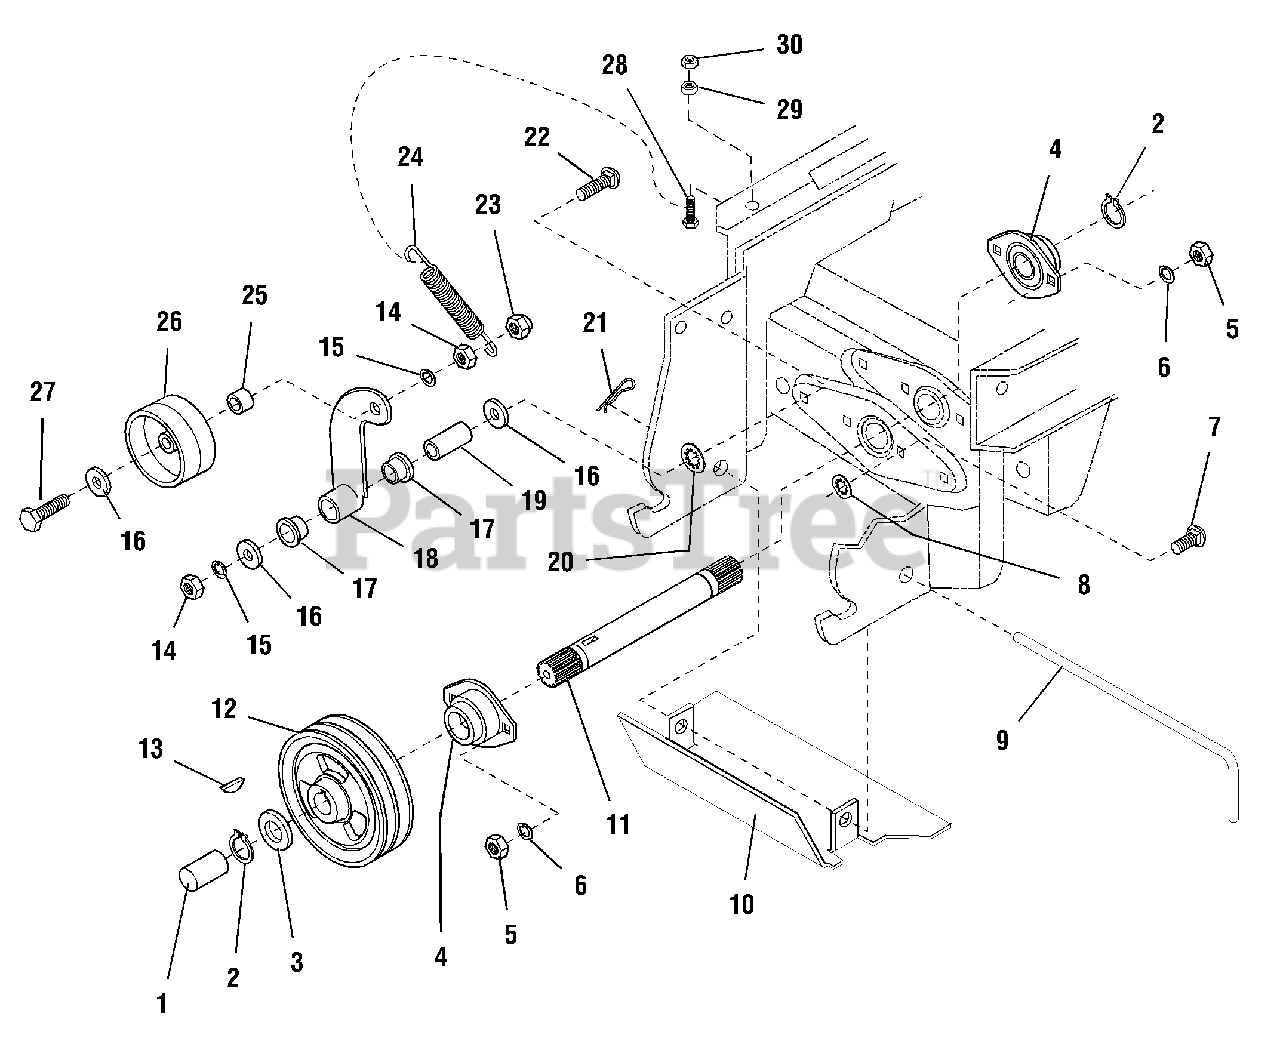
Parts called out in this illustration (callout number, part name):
1	COVER, PTO Shaft
2	RING, Retainer
3	WASHER, 1.0
4	BEARING, Ball
5	NUT, Hex, Full, 5/16-18
6	LOCKWASHER, 5/16
7	CARRIAGE BOLT, 5/16-18 x 7/8
8	NUT, Push, 5/16
10	GUARD PLATE, PTO
12	PULLEY, PTO
13	KEY, Hi Pro, 3/4 Dia.
14	NUT, Hex, Full, 3/8-16
15	LOCKWASHER, 3/8
16	WASHER, Plain, 3/8
17	BUSHING, 41/64 x 3/4 x 1/2
18	ARM ASSEMBLY, Idler
19	SPACER, 25/64 x 5/8 x 1-1/2
20	NUT, Push, 3/8
21	HAIRPIN, Cotter
22	CARRIAGE BOLT, 3/8-16 x 2-1/4
23	NUT, Hex, Flange Lock, 3/8-16
24	SPRING, Tension
25	SPACER, 25/64 x 5/8 x 5/8
26	PULLEY, Idler, 3-1/4 Dia.
27	CAPSCREW, Hex Hd., 3/8-16 x 2-1/2
28	CAPSCREW, Hex Hd, 5/16-18 x 1-1/4
29	NUT, Hex, Nylon Lock, 5/16-18
30	NUT, Hex Flange, Center Lock, 5/16
